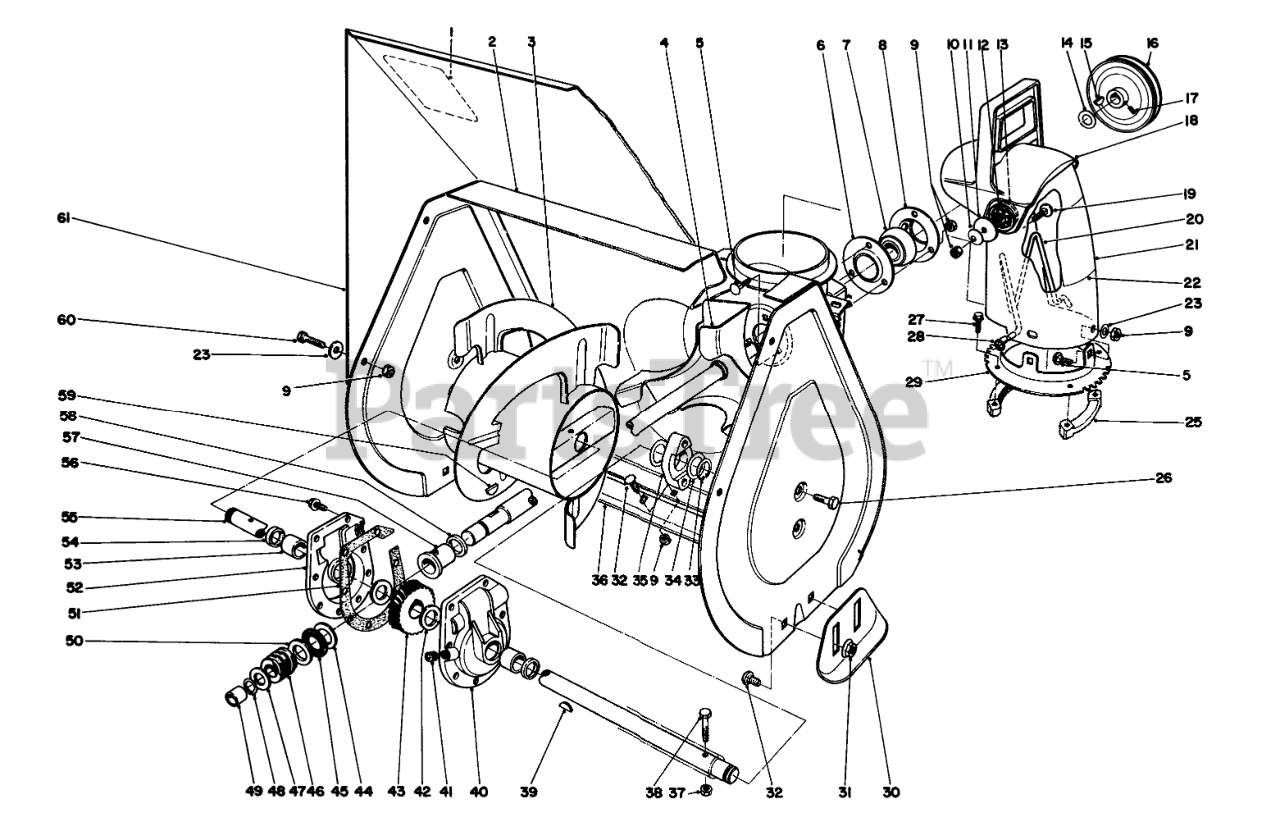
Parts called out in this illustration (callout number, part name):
1	DECAL-WARNING, AUGER
2	Housing-Auger (Incl. Ref. #1)
3	Auger R.H.
4	Shaft & Impeiler
5	SCREW-CARR
6	Flange-Bearing Front
7	BEARING-BALL
8	Flange-Bearing Rear
9	NUT-LOCK, NI
10	WASHER-BELLEVILLE
11	WASHER-FLAT
12	PLATE-FRICTION
13	WASHER-RUBBER
14	WASHER
15	KEY-WOODRUFF
16	PULLEY
17	SCREW-SET, SQH
18	CHUTE-DEFLECTOR
19	SCREW-CARR
20	WIRE-CHUTE
21	Chute-Discharge
22	Decal-Discharge
23	WASHER-PLAIN
25	RING-CHUTE, RETAINER
26	SCREW-HWHTF
27	SCREW-SPECIAL
28	NUT-PUSH
29	Chute Ring
30	Skid
31	NUT-HF
32	BOLT-CARR
33	RING-RETAINING
34	WASHER
35	BEARING-AUGER
36	Blade-Scraper
37	NUT-LOCK, NI
38	SCREW-HH
39	KEY-WOODRUFF
40	Gear Case L.H. (Incl. Ref. #53 & 54)
41	PLUG-PIPE, SQH
42	WASHER-THRUST
43	GEAR-WORM, 27T
44	WASHER-THRUST
45	BEARING-THRUST
47	WASHER-THRUST
48	Ring-Snap
49	BUSHING
50	WASHER-THRUST
51	GASKET-CASE, GEAR
52	Gear Case R.H. (Incl. Ref. #53 & 54)
53	BUSHING
54	SEAL-OIL
55	AUGER SHAFT
56	SCREW-TAPTITE
57	BUSHING-INPUT
58	RING-QUAD
59	KEY-WOODRUFF
60	SCREW-HH
61	AUGER EXT 21 SCAND
